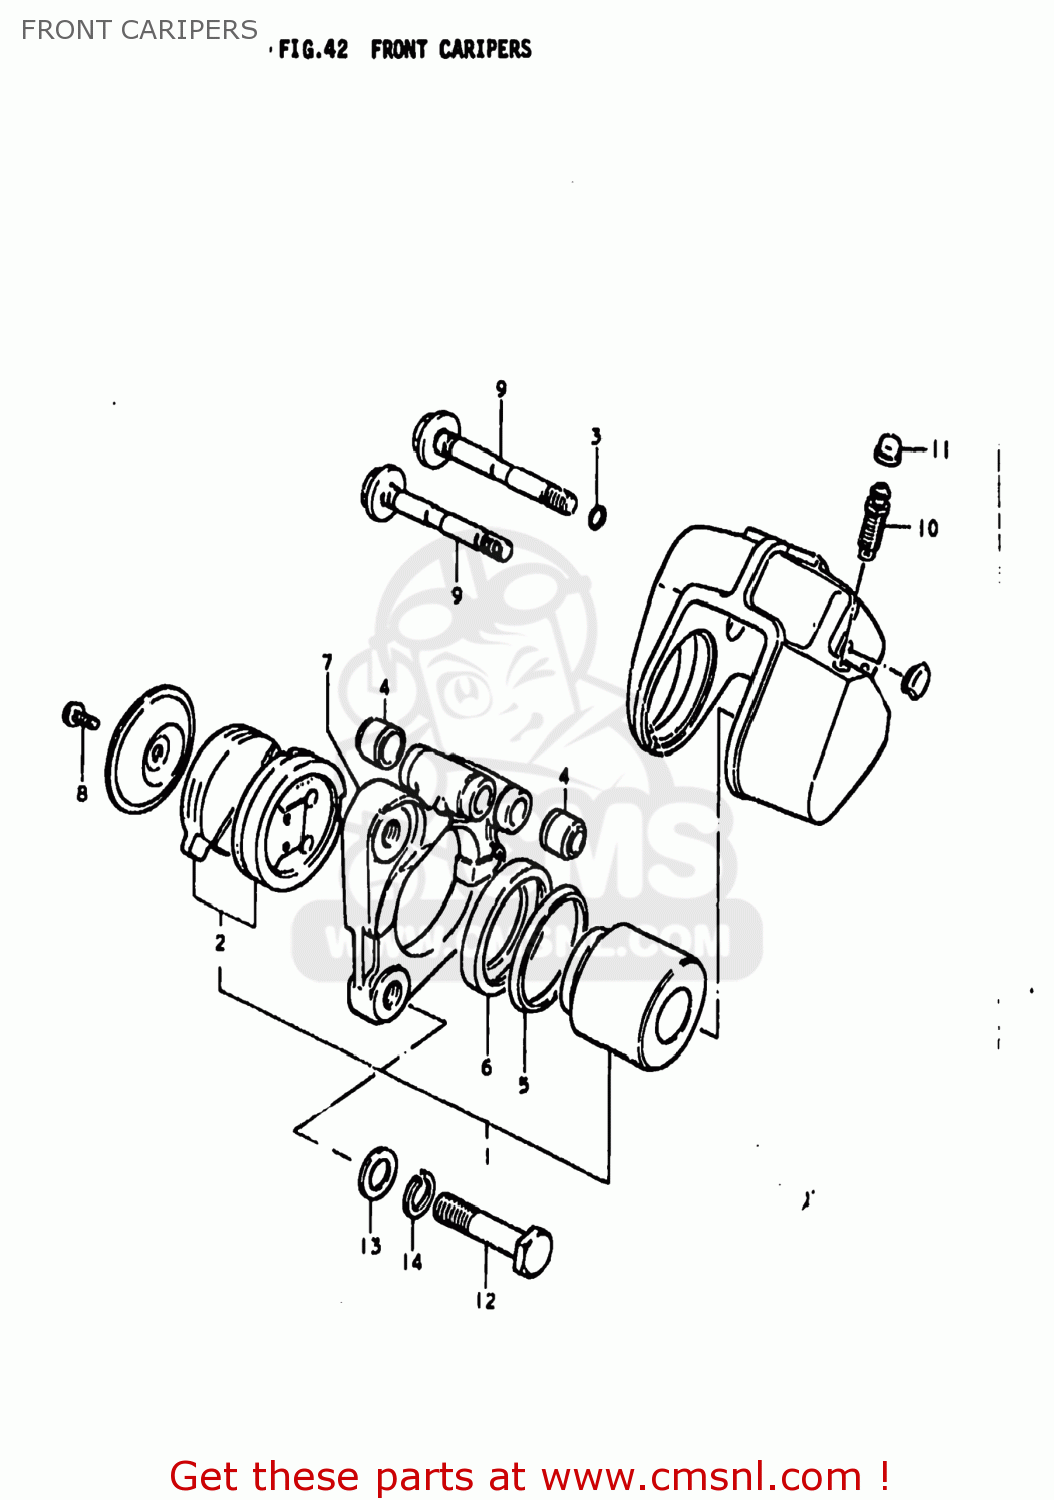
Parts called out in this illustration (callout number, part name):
0	CALIPER ASSEMBLY,FRONT,LEFT
1	PISTON & PAD SET
2	PAD SET (MCA)
3	O RING
4	COVER,AXLE DUST
5	SEAL,PISTON
6	BOOT,PISTON
7	HOLDER, CARIPERS RH
8	SCREW 6X12
9	AXLE,CALIPER
10	BLEEDER
11	CAP,BLEEDER PL
12	BOLT
13	WASHER
14	LOCK WASHER
